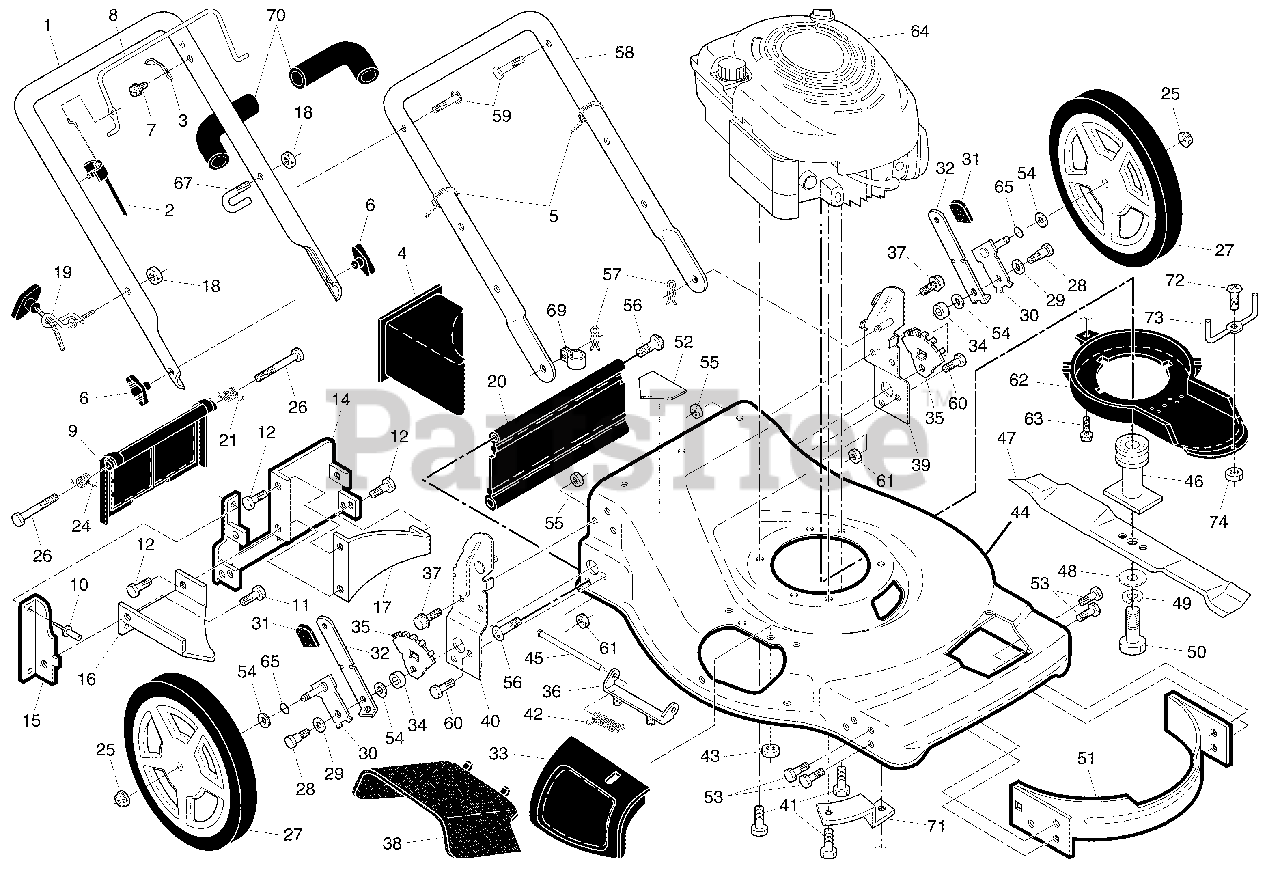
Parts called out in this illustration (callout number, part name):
1	Upper Handle
2	Engine Zone Control Cable
3	Bracket, Upstop
4	Mulcher Plug
5	Wire Tie
6	Handle Knob
8	Control Bar
9	Rear Door Assembly
11	Screw, Self-Tapping #10-24 x 5/8
12	Screw, Hex Hex Head, Sems 1/4-20 x 1/2
14	Back Plate
15	Side Baffle
16	Discharge Baffle
17	Rear Baffle
18	Keps Locknut 1/4-20
19	Rope Guide
20	Rear Skirt
21	Spring, Rear Door, LH
24	Spring, Rear Door, RH
25	Nut, Hex, Flanged
26	Bolt, Rear Door
27	Wheel, Rear
28	Bolt, Shoulder 3/8-16 x 1
29	Washer, Belleville
30	Axle Arm Assembly
31	Selector Knob
32	Selector Spring
33	Mulcher Door
34	Spacer
35	Wheel Adjusting Bracket
36	Hinge Bracket Assembly
37	Screw, Sems, Thread Cutting 5/16-18 x 3/4
38	Discharge Deflector
39	Handle Bracket Assembly, LH
40	Handle Bracket Assembly, RH
42	Spring, Torsion
43	Nut, Hex, Nylock
44	Kit, Lawn Mower Housing
45	Rod, Hinge
46	Blade Adapter / Pulley
47	Blade, 22"
48	Washer, Hardened
49	Washer, Helical
50	Screw, Machine, Hex Head 3/8
51	Front Baffle
52	Danger Decal
55	Locknut, Hex 3/8-16
56	Screw, Hinge 1/4-20 x 1-1/4
57	Hairpin Cotter
58	Lower Handle
59	Handle Bolt
61	Nut
62	Debris Shield
63	Screw, Debris Shield
67	Clip, Packaging
69	Clip, Cable
71	Mounting Bracket, Debris Shield
73	Belt Keeper
